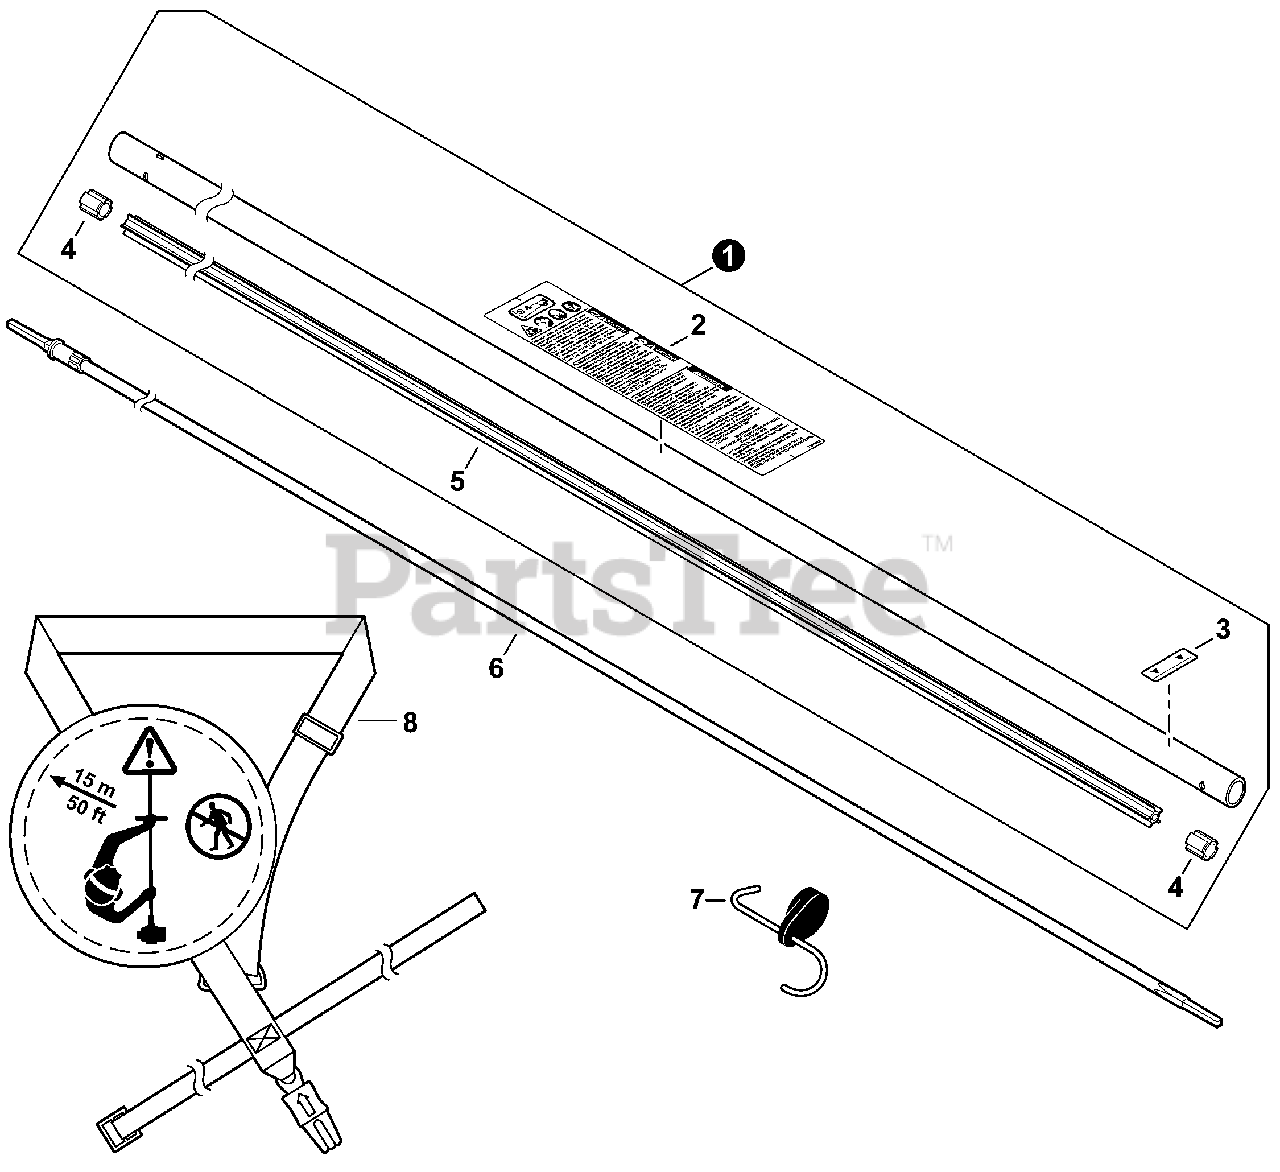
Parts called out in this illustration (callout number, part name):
1	MAIN PIPE ASSY
2	LABEL, CAUTION
3	LABEL - ALIGNMENT
5	LINER - FLEXIBLE
6	DRIVESHAFT - FLEXIBLE
7	HANGER, ATTACHMENT
8	HARNESS, SHOULDER
